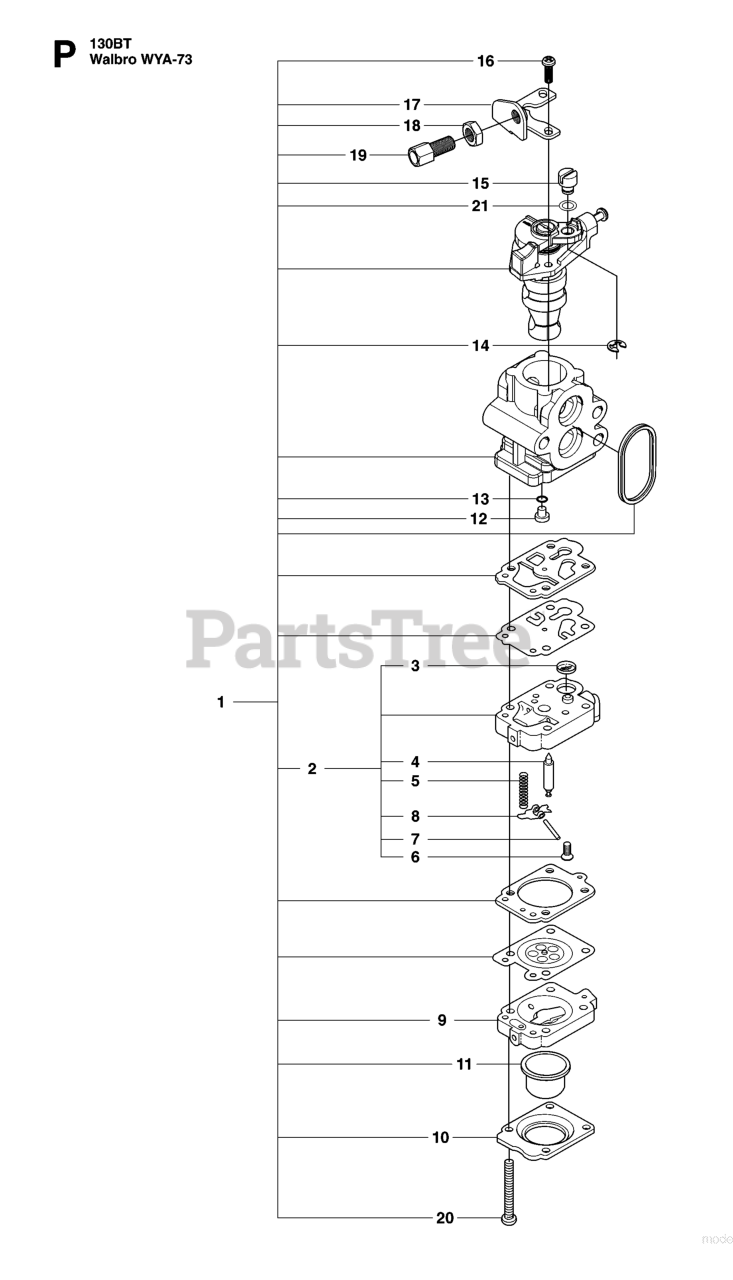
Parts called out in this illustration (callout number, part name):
1	CARBURETOR A
2	CARBURETOR BODY
9	BODY
10	COVER
11	PUMP
13	O-RING
15	SWIVEL
16	SCREW
17	RP_BRACKET
18	NUT
19	SCREW
20	SCREW
21	WASHER
